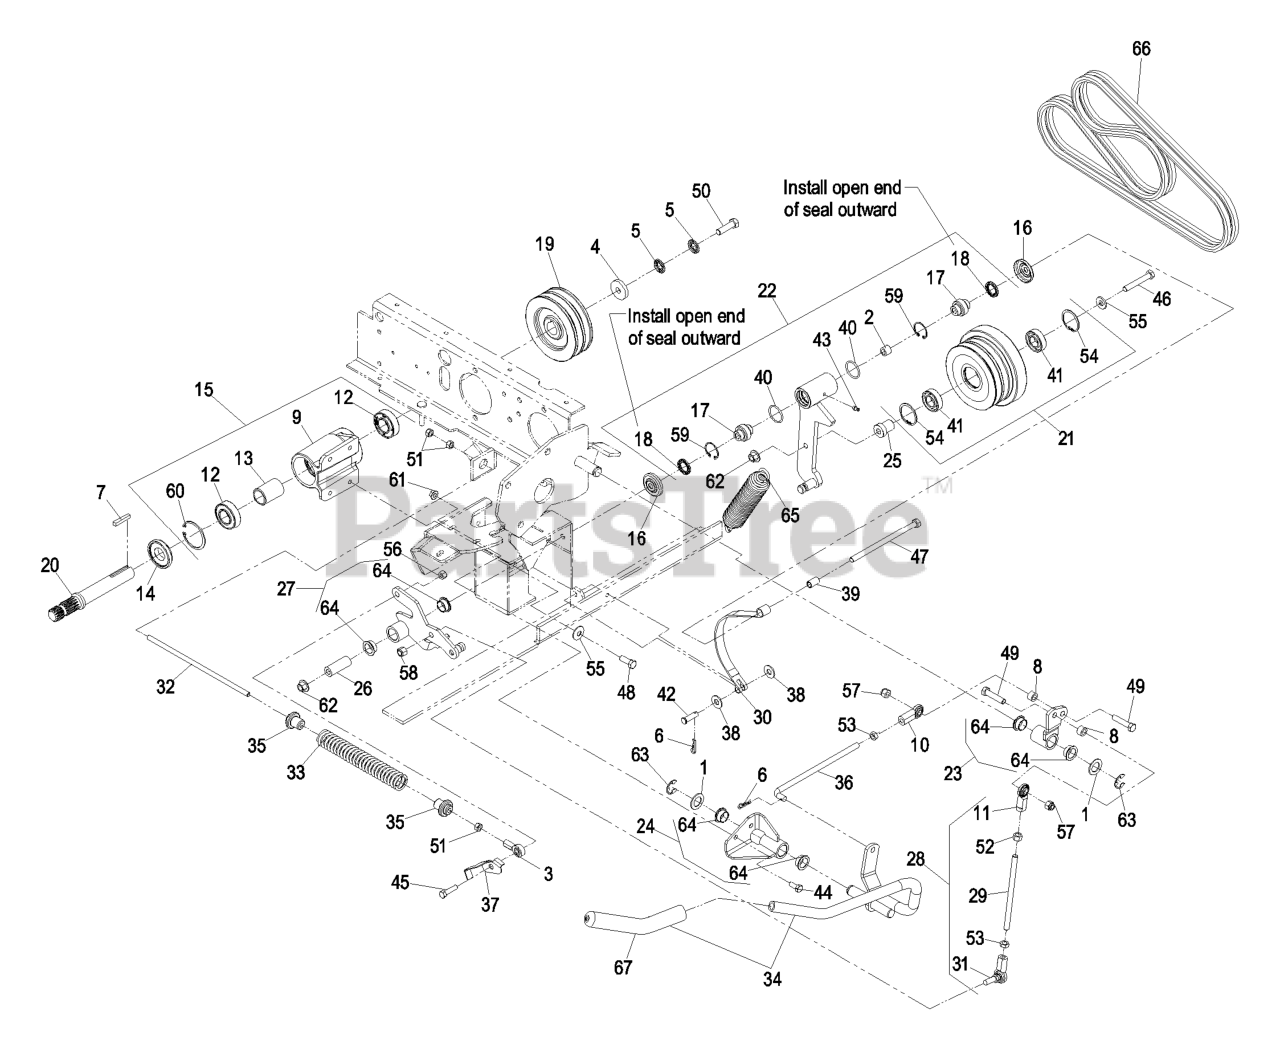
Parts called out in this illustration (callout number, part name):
2	BUSHING-LEVER, LIFT
3	BALLJOINT-RH
4	WASHER-CLUTCH
5	WASHER-SPRING
6	PIN-COTTER
7	KEY-SQUARE
10	JOINT-BALL, END
11	JOINT-BALL END, LH
12	BEARING-JACKSHAFT
13	SPACER-BEARING
14	SPACER-GUARD, BOTTOM
16	GUARD-TOP
17	BEARING-SPHERICAL
18	SEAL-LIP, SINGLE
20	SHAFT-JACK
21	IDLER SHEAVE ASM
22	IDLER PIVOT ASM
23	ARM ASM
24	PIVOT ASM
25	SPACER-IDLER
26	BUSHING
27	ARM ASM
28	CLUTCH LINK ASM
29	ROD-LINKAGE
30	BAND-BRAKE
31	BALLJOINT-RH
32	LINKAGE-ROD, PTO BRAKE
33	SPRING-BRAKE
34	PTO HANDLE ASM
35	BUSHING-SPRING
36	LINK-HANDLE
37	SWITCH-FLAG
38	WASHER-FLAT
41	BEARING-BALL
42	PIN-CLEVIS
43	FITTING-GREASE
44	SCREW-HH
45	SCREW-HH
46	BOLT-CARR
47	SCREW-HH
48	SCREW-HH
49	SCREW-HH
50	SCREW-HH
51	NUT-HEX
52	NUT-HEX, LH
53	NUT-HEX
54	RING-RETAINING
55	WASHER-BELLEVILLE
56	NUT-LOCK, NI
57	NUT-LOCK, NI
58	NUT-LOCK
59	RING-SNAP
60	RING-SNAP
62	NUT-FLANGE
64	BUSHING-BRONZE
65	SPRING-EXTENSION
66	BELTS-MATCHED PAIR
67	GRIP-LEVER, CONTROL
